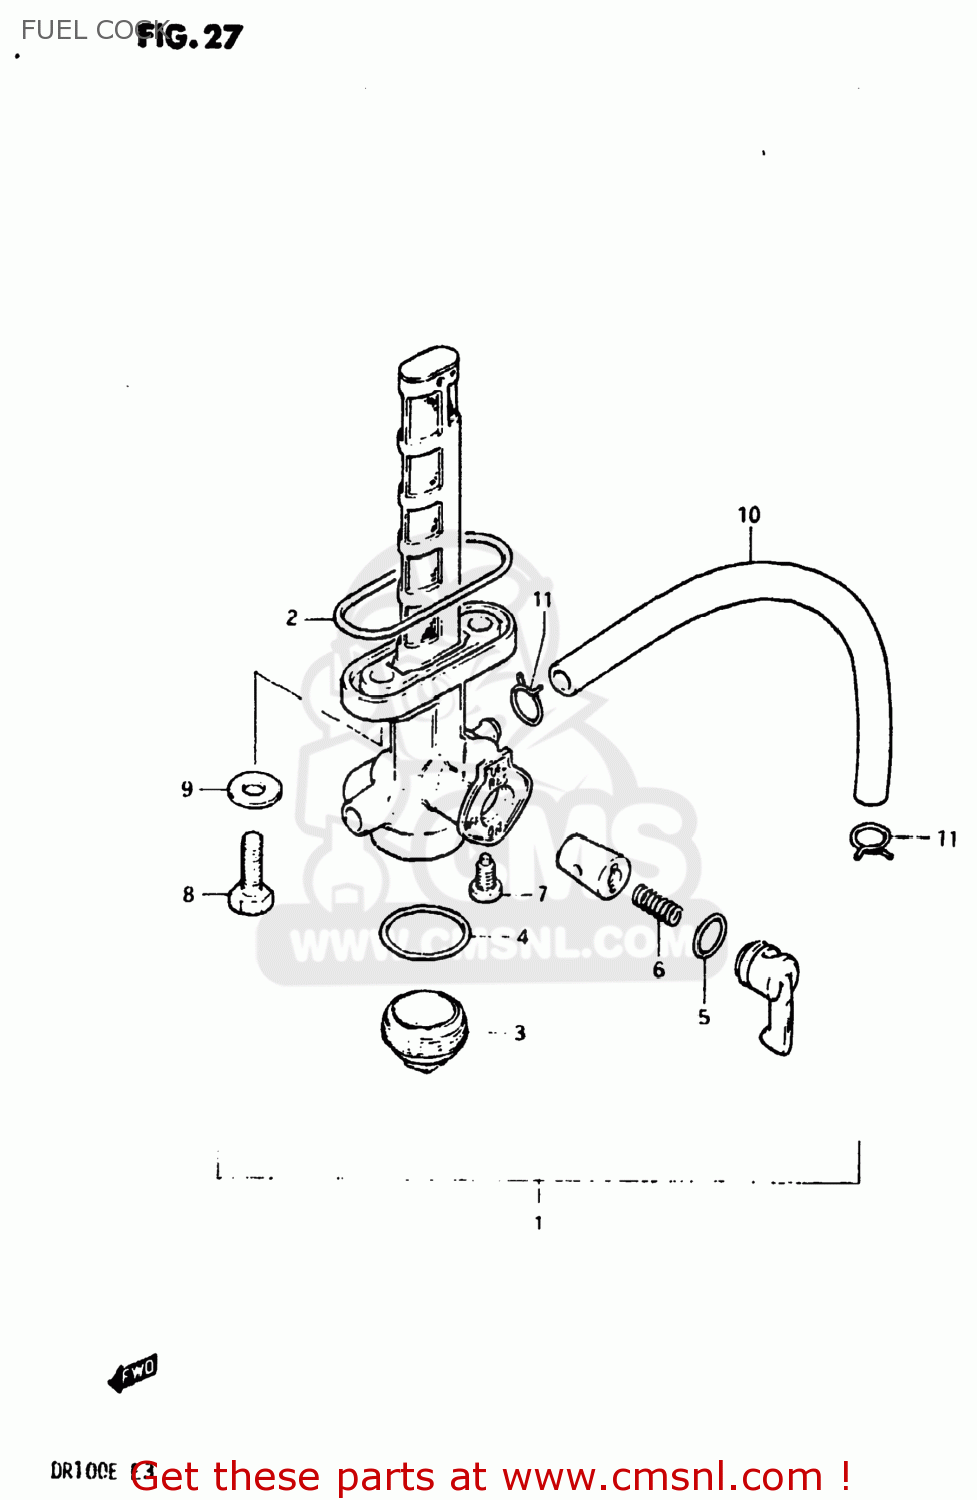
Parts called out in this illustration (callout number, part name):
1	COCK ASSEMBLY,FUEL
2	O RING,FUEL COCK
3	CUP,STRAINER
4	GASKET,FILTER (NAS)
5	O-RING
6	SPRING
7	SCREW
8	BOLT(6X20)
9	GASKET
10	HOSE
11	CLIP
